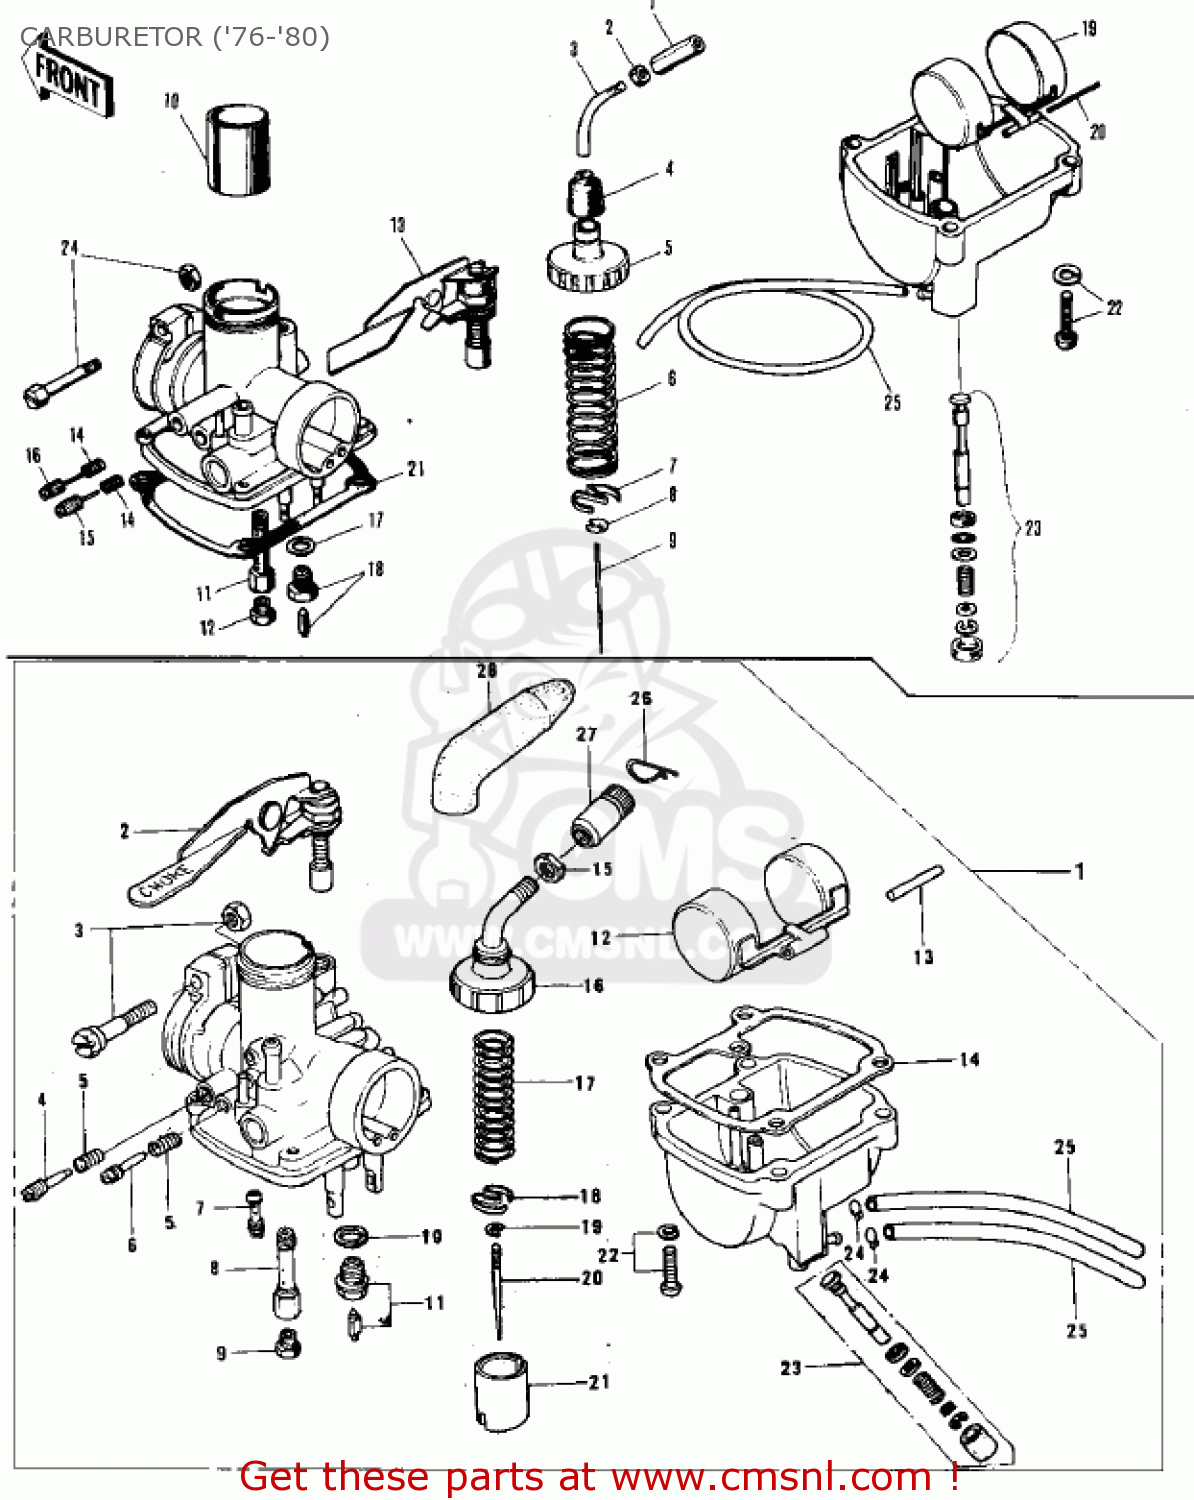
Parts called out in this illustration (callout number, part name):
1	CABLE ADJUSTER
2	PLUNGER-STARTER
3	GUIDE
4	CAP-RUBBER
5	TOP-MIXING CHAMBER
6	SCREW,THROTTLE STOP
7	JET-PILOT,#A15
8	CLAMP,E-TYPE
9	JET NEEDLE 3G09
10	WASHER-VALVE SEAT
11	NEEDLE JET E-O
12	FLOAT
13	FLOAT PIN
14	SPRING-THR STOP SCREW
15	SCREW,THROTTLE STOP
16	SCREW-PILOT AIR
17	WASHER-VALVE SEAT
18	FLOAT VALVE ASSY
19	FLOAT
20	FLOAT PIN
21	VALVE,THROTTLE,CA2.0
22	SCREW-FLOAT CHAMBER
23	EJECTOR ASSY-FUEL
24	CLAMP,TUBE
25	TUBE,OVERFLOW,3X5X200
26	CIRCLIP
27	ADJUSTER-CABLE,THROTT
28	BOOTS,CABLE ADJUSTER
